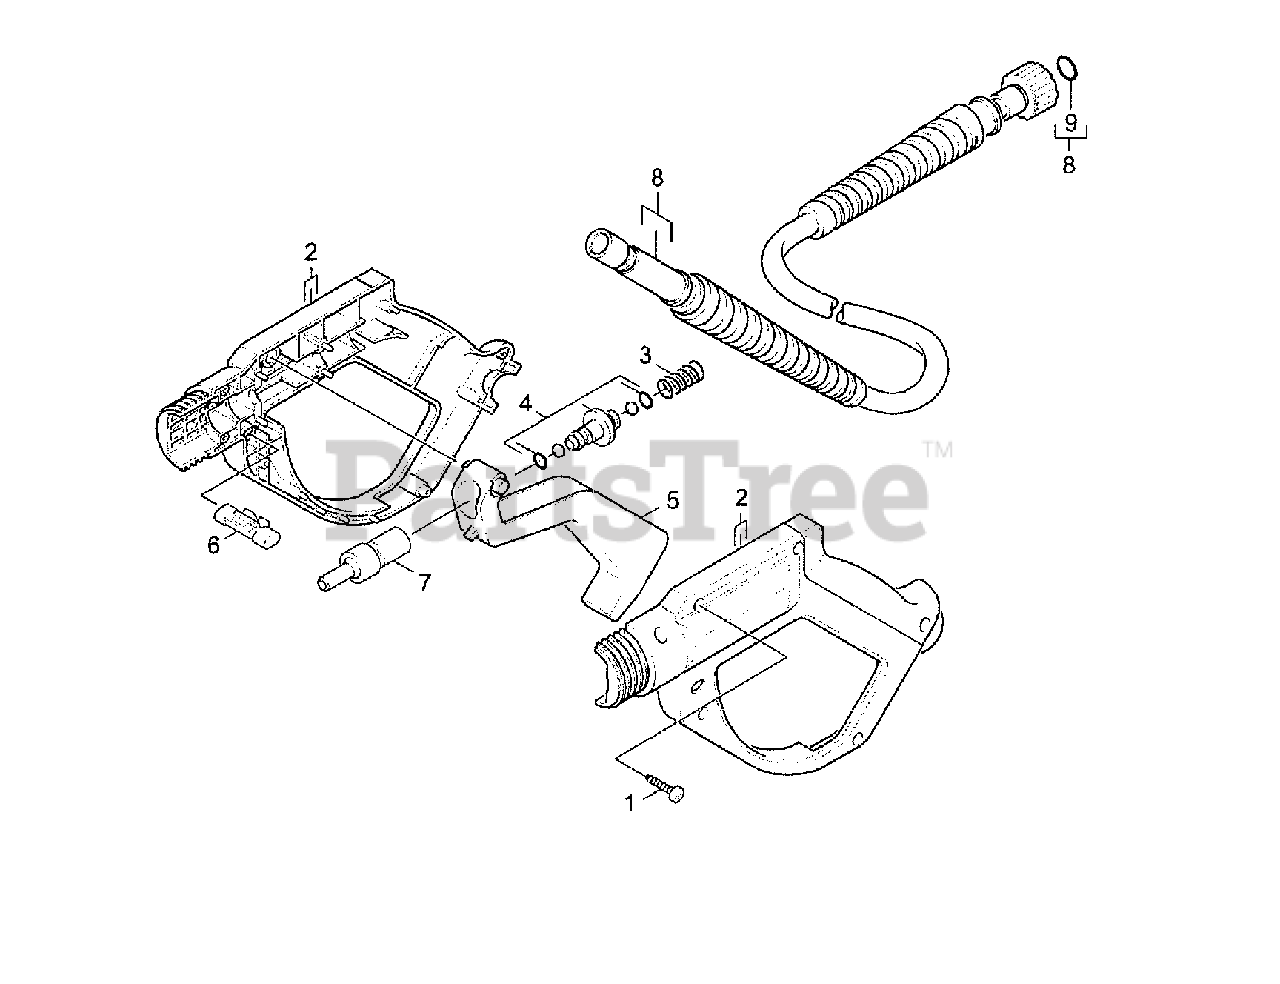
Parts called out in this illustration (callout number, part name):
2	Handle, Right and Left Side
7	Valve Housing
8	High Pressure Hose
